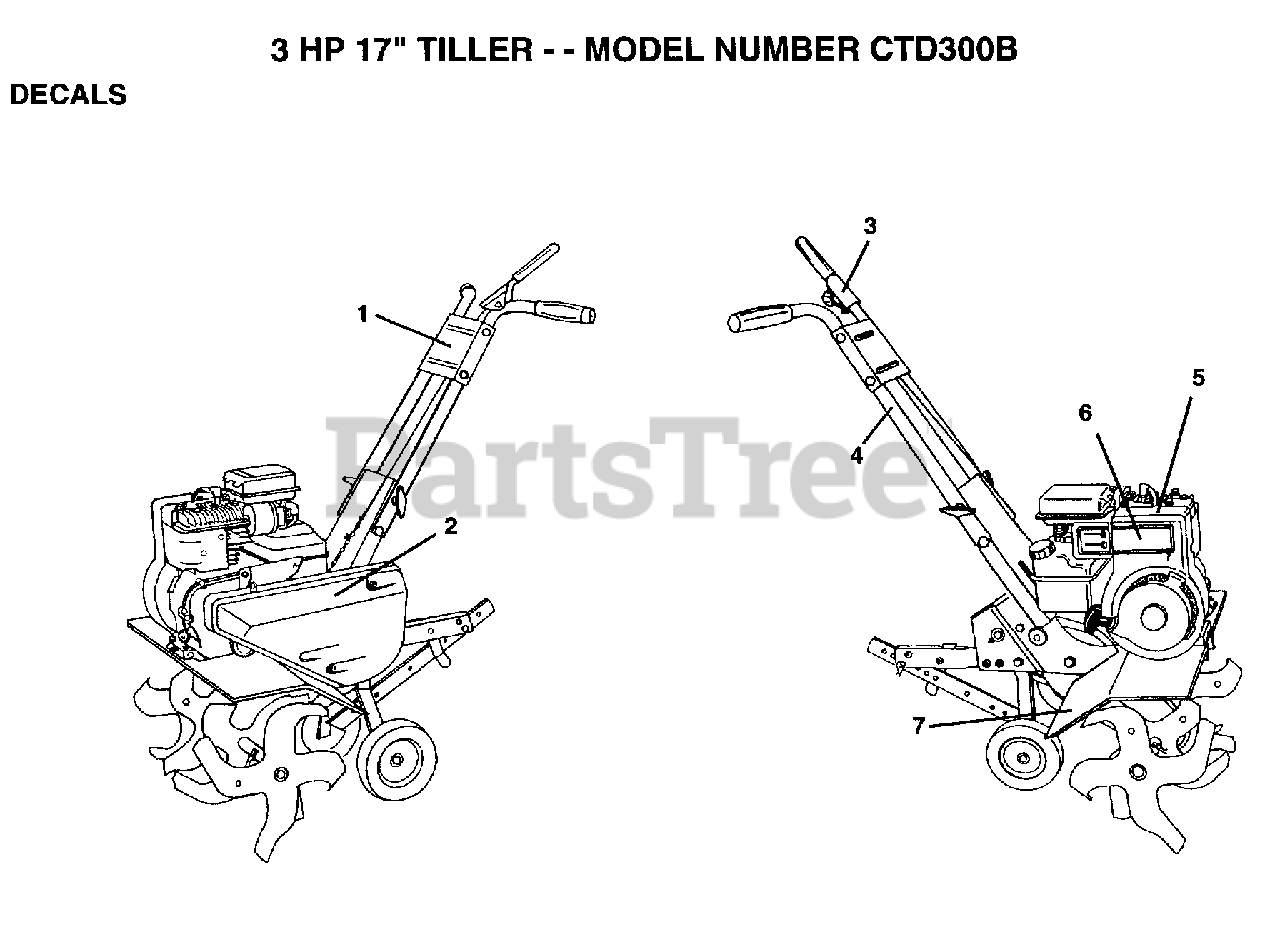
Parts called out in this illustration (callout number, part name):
1	DECAL PNL CNTL
2	DECAL.GUARD.BELT
3	DECAL TI
4	DECAL TI
6	"DECAL,ENG HP"
7	DECAL TI
